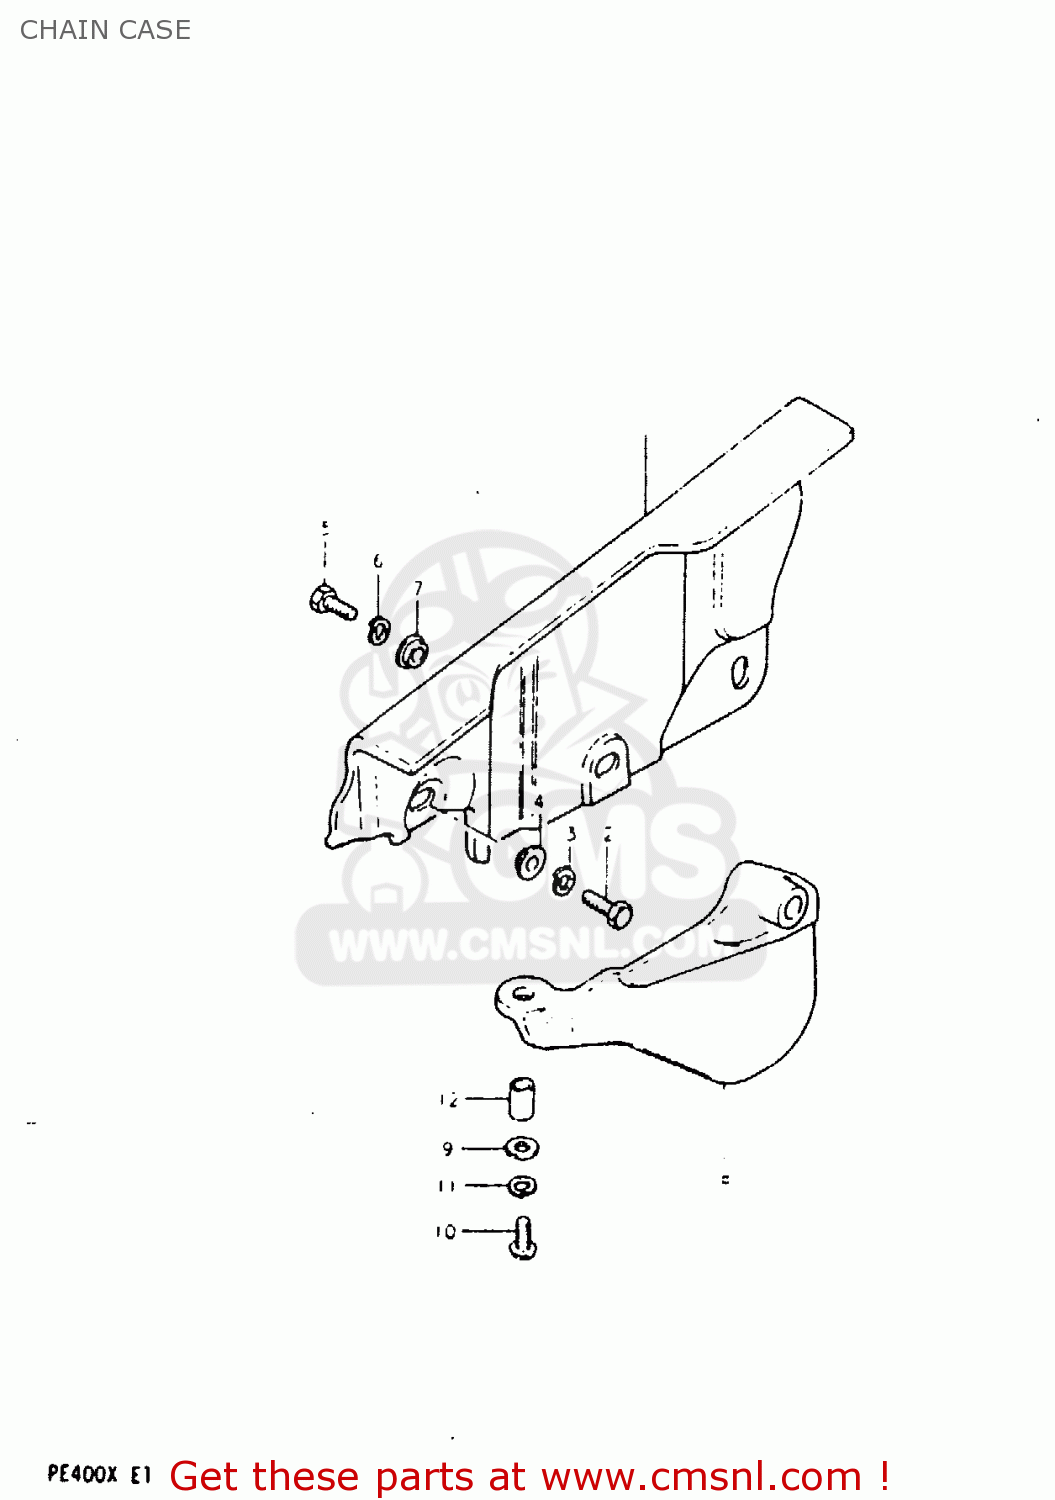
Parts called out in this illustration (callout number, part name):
1	CASE,CHAIN
2	BOLT, UPPER
3	LOCK WASHER
4	WASHER(5.5X10X0.8)
5	BOLT
6	LOCK WASHER
7	WASHER
8	RUBBER,CHAIN CASE,LOWER
9	WASHER(6.5X18X1)
10	SCREW 6X12
11	LOCK WASHER
12	SPACER (6.1X8X5.2)
